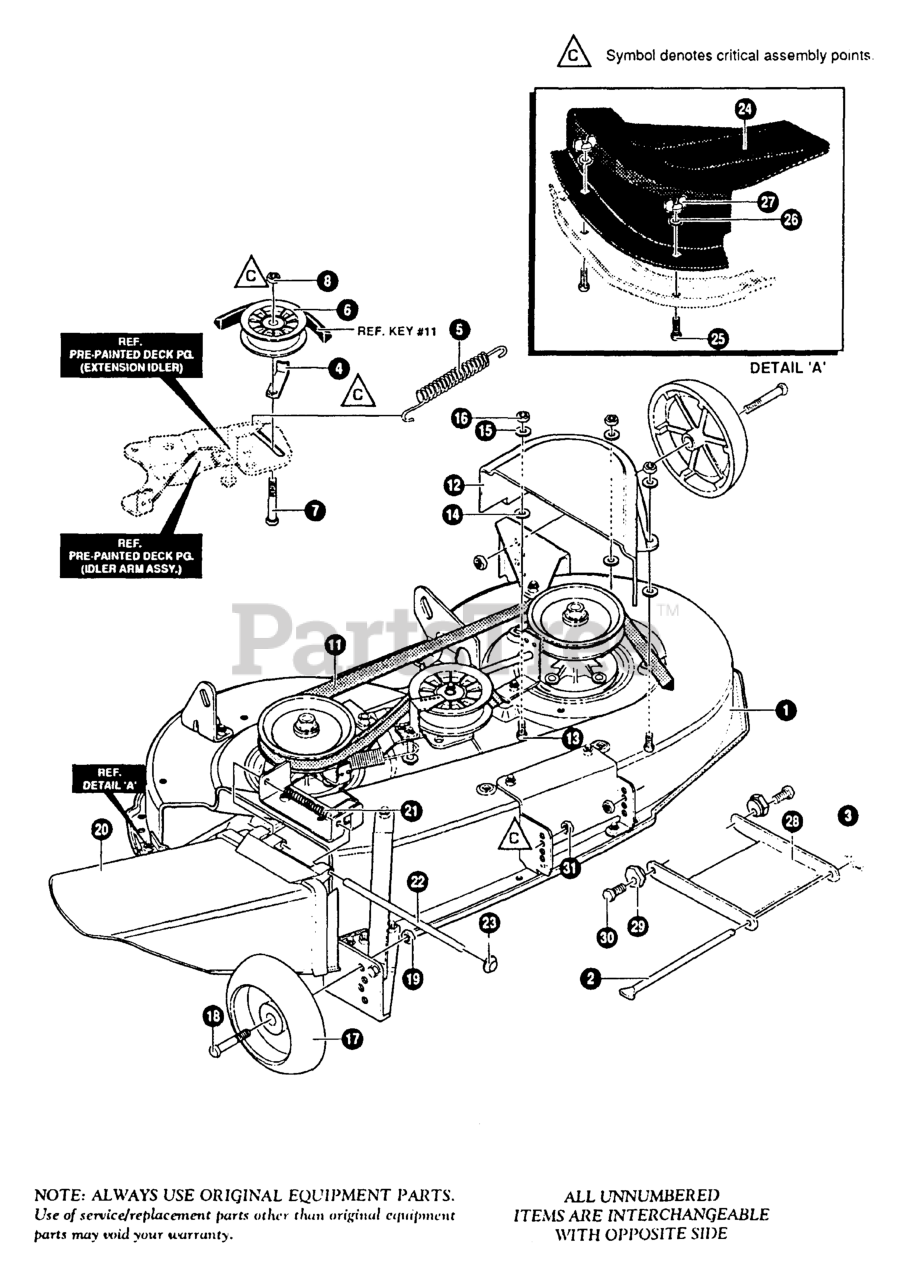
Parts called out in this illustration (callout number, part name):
2	ROD, DECK HITCH
3	PIN, HAIR
4	RETAINER, BELT
5	SPRING, TENSION
6	PULLEY, IDLER
7	BOLT, 3/8-16 X 1.75
8	NUT, 3/8-16
11	BELT, V 5L 86.00
12	GUARD, BELT LH
13	BOLT, 5/16-18 X .75
14	PUSHNUT, 5/16 BOLT RETAINER
15	WASHER, FLAT .344 X .69 X .065
16	NUT, 5/16-18
17	GAUGE WHEEL
18	BOLT, .500 X 1.390
19	NUT, 3/8-16
20	CHUTE DEFLECTOR
21	SPRING, TORSION
22	ROD, PIVOT DECK
23	NUT, PUSH ON CAP
24	MULCHER PLUG
25	BOLT, 5/16-18 X .75
26	WASHER, .320 X .61 X .03
27	NUT, WING 5/16 - 18
28	BRACKET, LINK DECK FRONT
29	NUT, ADJUST
30	SCREW, 5/16-18 x 1.00
31	NUT, 5/16-18
